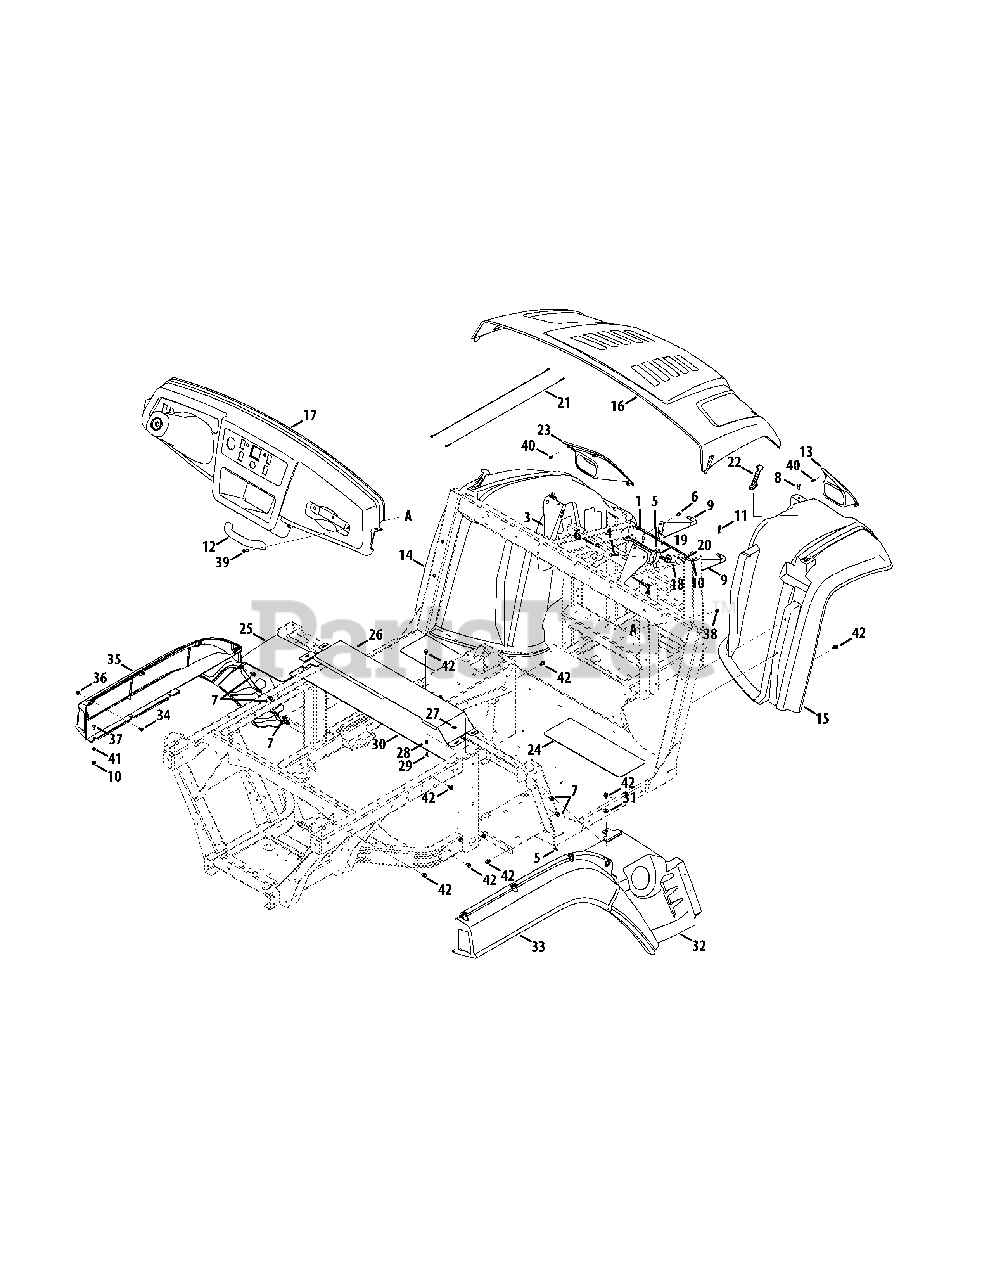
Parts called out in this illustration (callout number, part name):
2	Bracket, Hood/dash, Mount, Rh
3	Bracket, Hood/dash, Mount, Lh
4	Screw, 1/4-20, 1.75, Gr5, Std
5	Screw, #12-16 x .50
6	Screw, TT, 1/4-20 x .500
7	Screw, TT, 1/4-15 x .500
8	Hex Head Screw, 1/4-20 x 1.00
9	Rod Assembly, Hood Mount
10	Nut, Flange Lock, 1/4-20
11	Cotter Pin, Internal .08 x 1.42
12	Handle, W/Screw 400/500 S
13	Head Light RH
14	Fender, Lh 4x4
14	Fender, Lh 4x4, Camo
15	Fender, Rh 4x4
15	Fender, Rh 4x4, Camo
16	Hood, 4x4
16	Hood, 4x4, Camo
16	Hood, 4x4, Camo, Treestand
16	Hood, 4x4, Green
16	Hood, 4x4, Red
17	Dash, Uv 4x4
18	Roller, Latch, Hood
19	Spring, Latch, Hood
20	Washer, Flat, .283 x .75 x .030
21	Cable, Hood
22	Strap, Hood
23	Head Light LH
24	Pad, abrasive, toe plate (4x4)
25	Fender, Lwr Lh Rr
25	Fender, Lwr Lh Rr, Camo
27	Latch, Panel, 1/4 Turn
28	Spring, Comprs, .40 OD x .040 Dia.
29	Spring, Clip
30	Insulator, Cover, UV
31	Washer, Bell, .340 x .872 x .060
32	Fender, Lower Rh Rr
32	Fender, Lower Rh Rr Camo
33	Fender, Rh Rr
33	Fender, Rh Rr, Camo
34	Screw, Mach., 1/4-20 x .500
35	Fender, Lh Rr
35	Fender, Lh Rr, Camo
36	Nut, Acorn, 1/4-20
37	Screw, Crg, 1/4-20, .62, Gr2
38	Nut, Hex Lock., 1/4-20
39	Screw, Machine, 1/4-20 x 1.00
40	Screw, Tt, 1/4-20 x .625, Hxindwsh
41	Washer, Flat 1/4"
42	Screw, tt, 5/16-18 x 0.750
